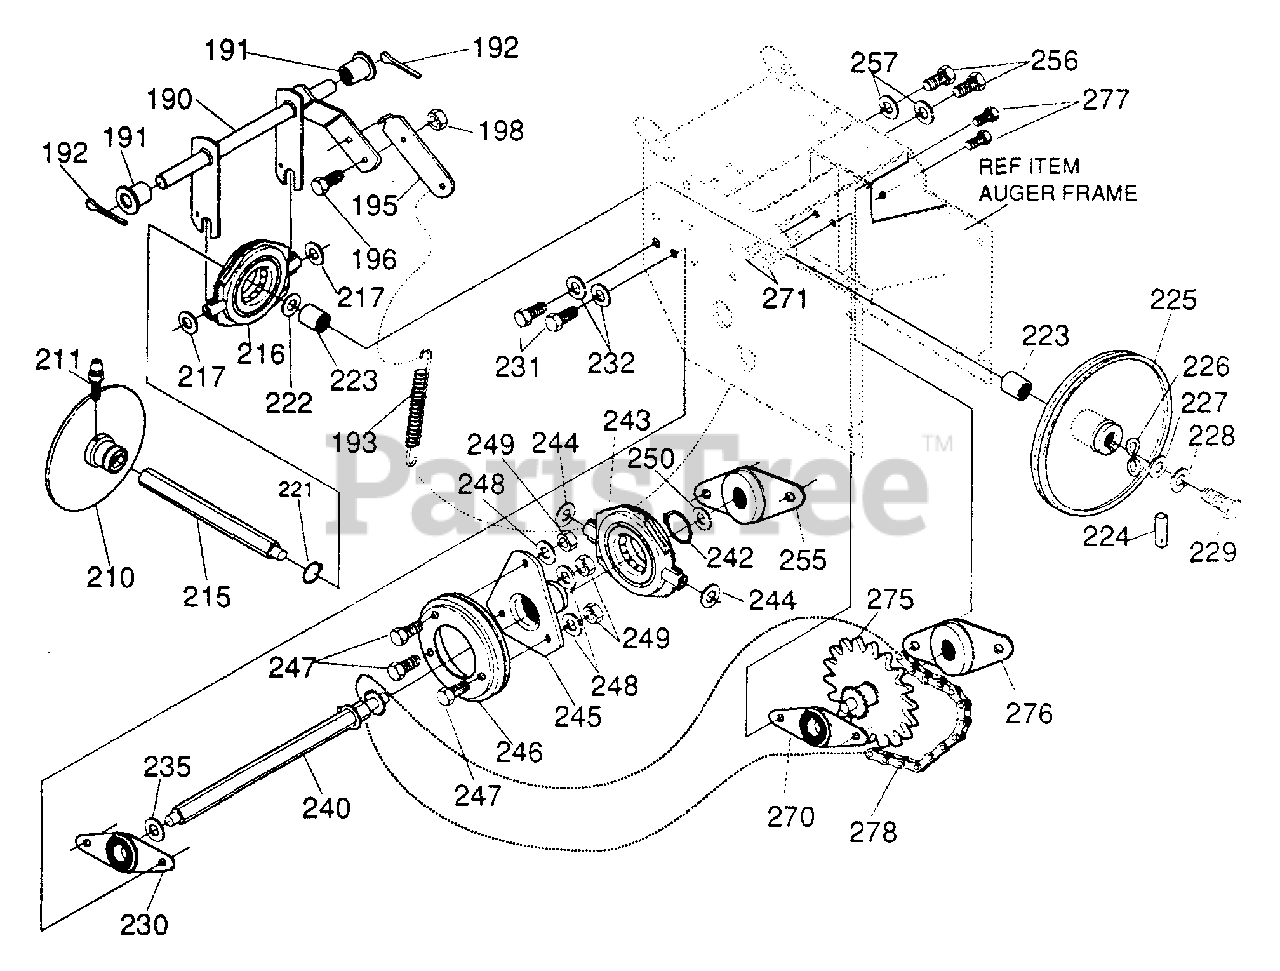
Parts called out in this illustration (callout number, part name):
190	LEVER, ASSY TRACT CLUTCH
191	BEARING, FLANGED
192	PIN, COTTER .125 DIA x 1.00 LG
193	SPRING, RETURN
195	LEVER, SPRING TRAC CL
196	SCREW, 1/4-20 x .63
198	NUT, 1/4-20 REGHEXCTRLK
210	DISC, ASSY FRICTION WHEEL
211	ZERK, GREASE .25-28 x 1.12 LONG
215	SHAFT, HEX TRACTION
216	BEARING, TRUNION 1.25 ID
217	FLATWASHER, .505 x 1.00 x .06
221	RING, RETEX 1.16 x .05
222	FLATWASHER, .680 x 1.12 x .060
223	BEARING, BALL 6203-2AA
224	KEY, SQUARE. 18 SQ x .63 LONG
225	PULLEY, V31- 6.50 x .56
226	WASHER, WAVE .675 x 1.00 x .020
227	FLATWASHER, .281 x 1.00 x .063
228	WASHER, SPTLK .263 x .49 x .07
229	SCREW, 1/4-20 x .75
230	BEARING & RETAINER ASSY
231	SCREW, 5/16-18 x .50 WAHHTAP
232	WASHER, SPTLK.328 x .60 x .09
235	WASHER, SP .502 x .75 x .0605
240	SHAFT & SPRKT, ASSY #40-8T
242	RING, RETEX 1.16 x .05
243	BEARING, TRUNION 1.25 ID
244	FLATWASHER, .505 x 1.00 x .06
245	HUB, FRICTION WHEEL
246	WHEEL, FRICTION DISC 4.375 OD
247	SCREW, 1/4-20 X .63
248	WASHER, SPTLK .26 X .50 x .06
249	NUT, 1/4-20 REGHEX
250	WASHER, SP .502 x .75 x .0605
255	BEARING & RETAINER ASSY
256	SCREW, 5/16-18 X .50
257	WASHER, SPTLK .328 X .60 x .09
270	BEARING & RETAINER ASSY
271	SCREW, 5/16-18 X .50
275	SPROCKET, ASSY 8T & 36T-41
276	BEARING & RETAINER ASSY
277	SCREW, 5/16-18 X .50
278	CHAIN, ROLLER #42 x 40
